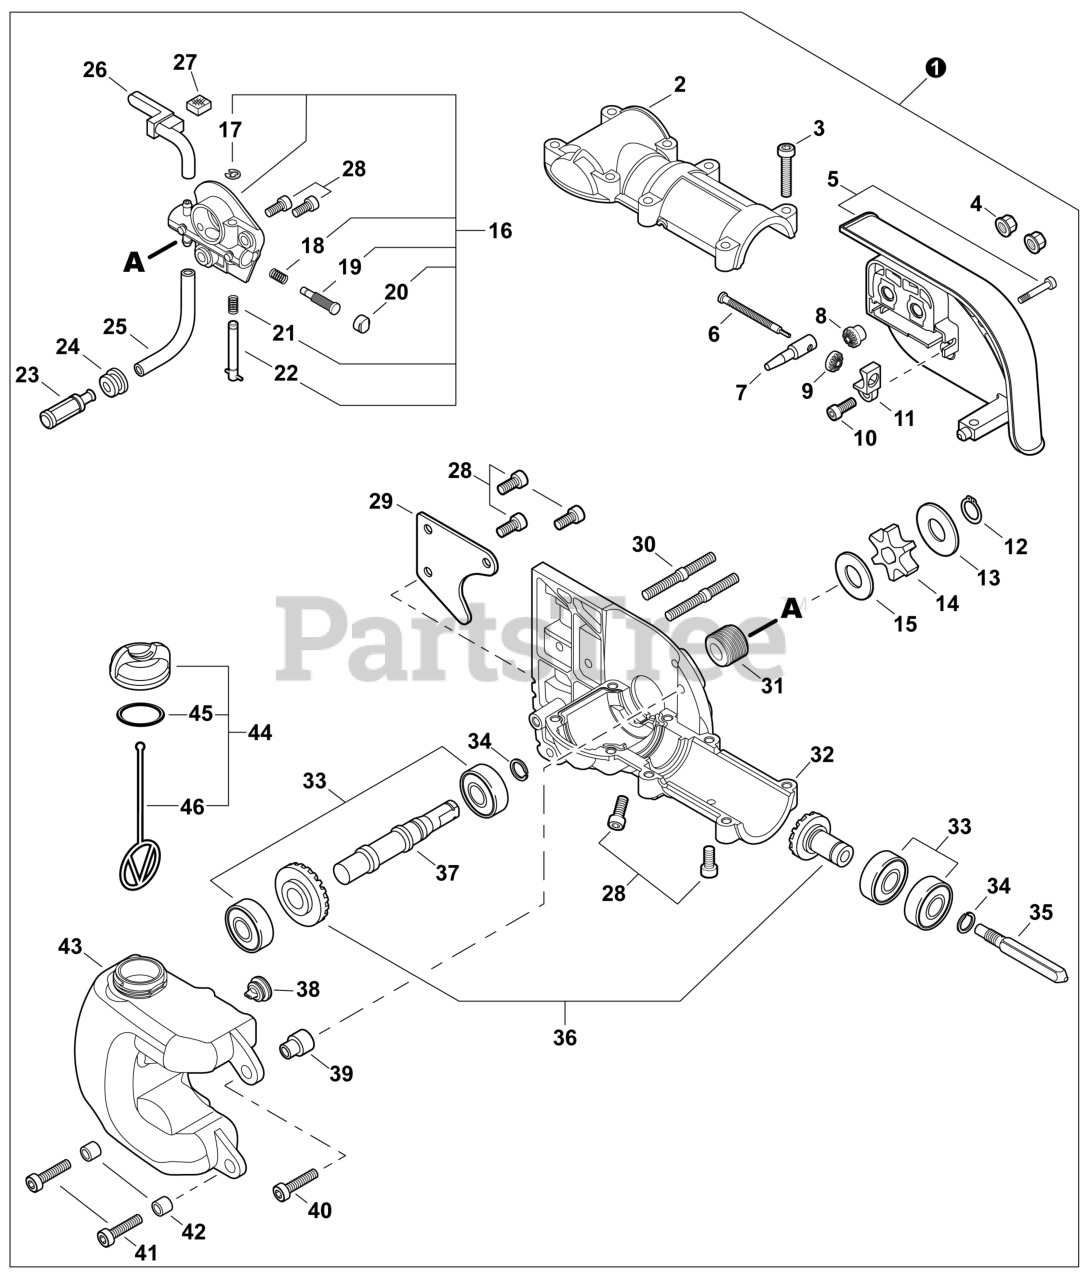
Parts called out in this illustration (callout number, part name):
1	GEAR CASE ASSY
2	CASE, GEAR - UPPER 35
3	BOLT, TORX 5x25
4	NUT, FLANGE M6
5	GUARD, SPROCKET
7	TENSIONER, CHAIN
8	GEAR - 14 TOOTH
9	GEAR - 14 TOOTH
10	SCREW 4
11	COLLAR 8
12	RING, SNAP
13	WASHER 10
14	SPROCKET, DRIVE
15	WASHER 10.2x24.5x1.2
16	AUTO-OILER ASSY
19	PLUNGER ASSY
20	CAP, PLUNGER
22	ADJUSTER, OILER
23	FILTER, OIL
25	PIPE 3x6x70
26	PIPE, OIL OUTLET
27	PAD, FOAM
28	BOLT, TORX 5x10
30	BOLT, STUD 6
31	GEAR, WORM
32	CASE, GEAR
33	BEARING, BALL
34	RING, SNAP 12
35	CONNECTOR, DRIVESHAFT
36	GEAR SET, BEVEL
37	SHAFT, GEAR
38	VENT ASSY
39	COLLAR 6
40	BOLT, TORX 5x25
41	BOLT, TORX 5x20
42	SPACER 6.2x7.8x6
43	TANK, OIL
44	CAP ASSY
45	O-RING 18
46	CONNECTOR, CAP L= 60 MM
